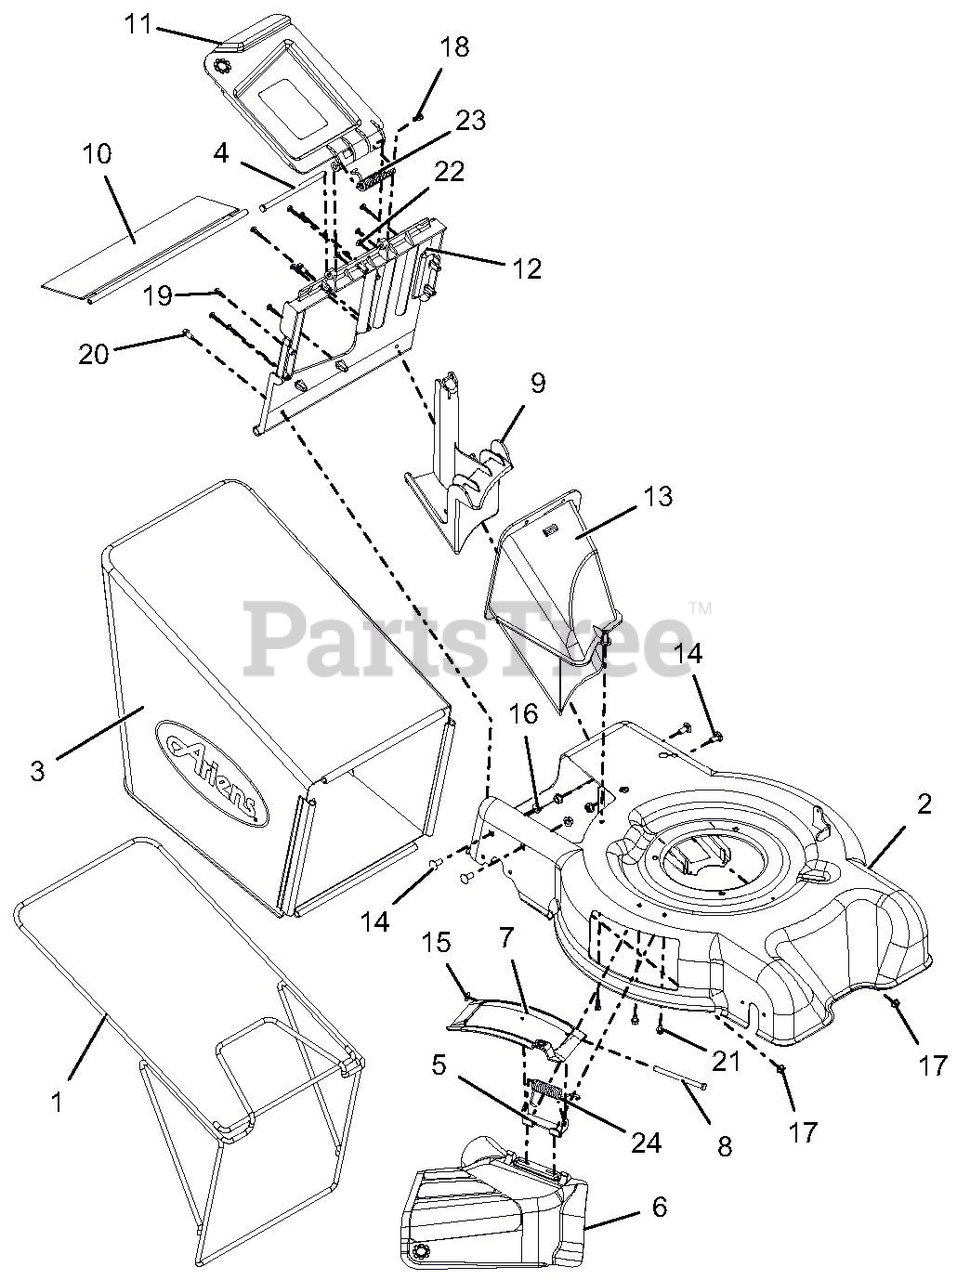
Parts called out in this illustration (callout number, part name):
1	FRAME, BAG
2	DECK, RAZOR W/ SAFETY DECALS
3	BAGGER, ARIENS LM
4	PIN, 5/16 X 5.80"
5	BRKT, HINGE LM
6	CHUTE, SIDE DISCHARGE - LM
7	COVER, SIDE DISCHARGE - LM
8	PIN, HINGE
9	PLUG, MULCH
10	GUARD, REAR DECK
11	REAR DOOR W/ SAFETY DECAL
12	HANGER, REAR BAG
13	CHUTE, REAR DISCHARGE LM
14	@BLT-RDHDSQNK .31-18X.75 G5YZ
15	NUT-PUSH .312
16	@NUT-LK-TOP-FLG .31-18 YWZC
17	@NUT-LK-TOP-FLG .25-20 YWZC
18	PIN-HAIR INT .08X.18X1.18 YWZC
19	SCR-TAP 12-14X.75PLSTITE @BLZC
20	@SCR-TAP .25-20X.62 HWH TR YWZ
21	@SCR-TAP .25-20X.37 HWH YWZ TR
22	PLUG,5/16 HOLE,.125 MATL PLSTC
23	SG-TORS .120X.68X3.09
24	SPRING, SIDE DISCHARGE DOOR
